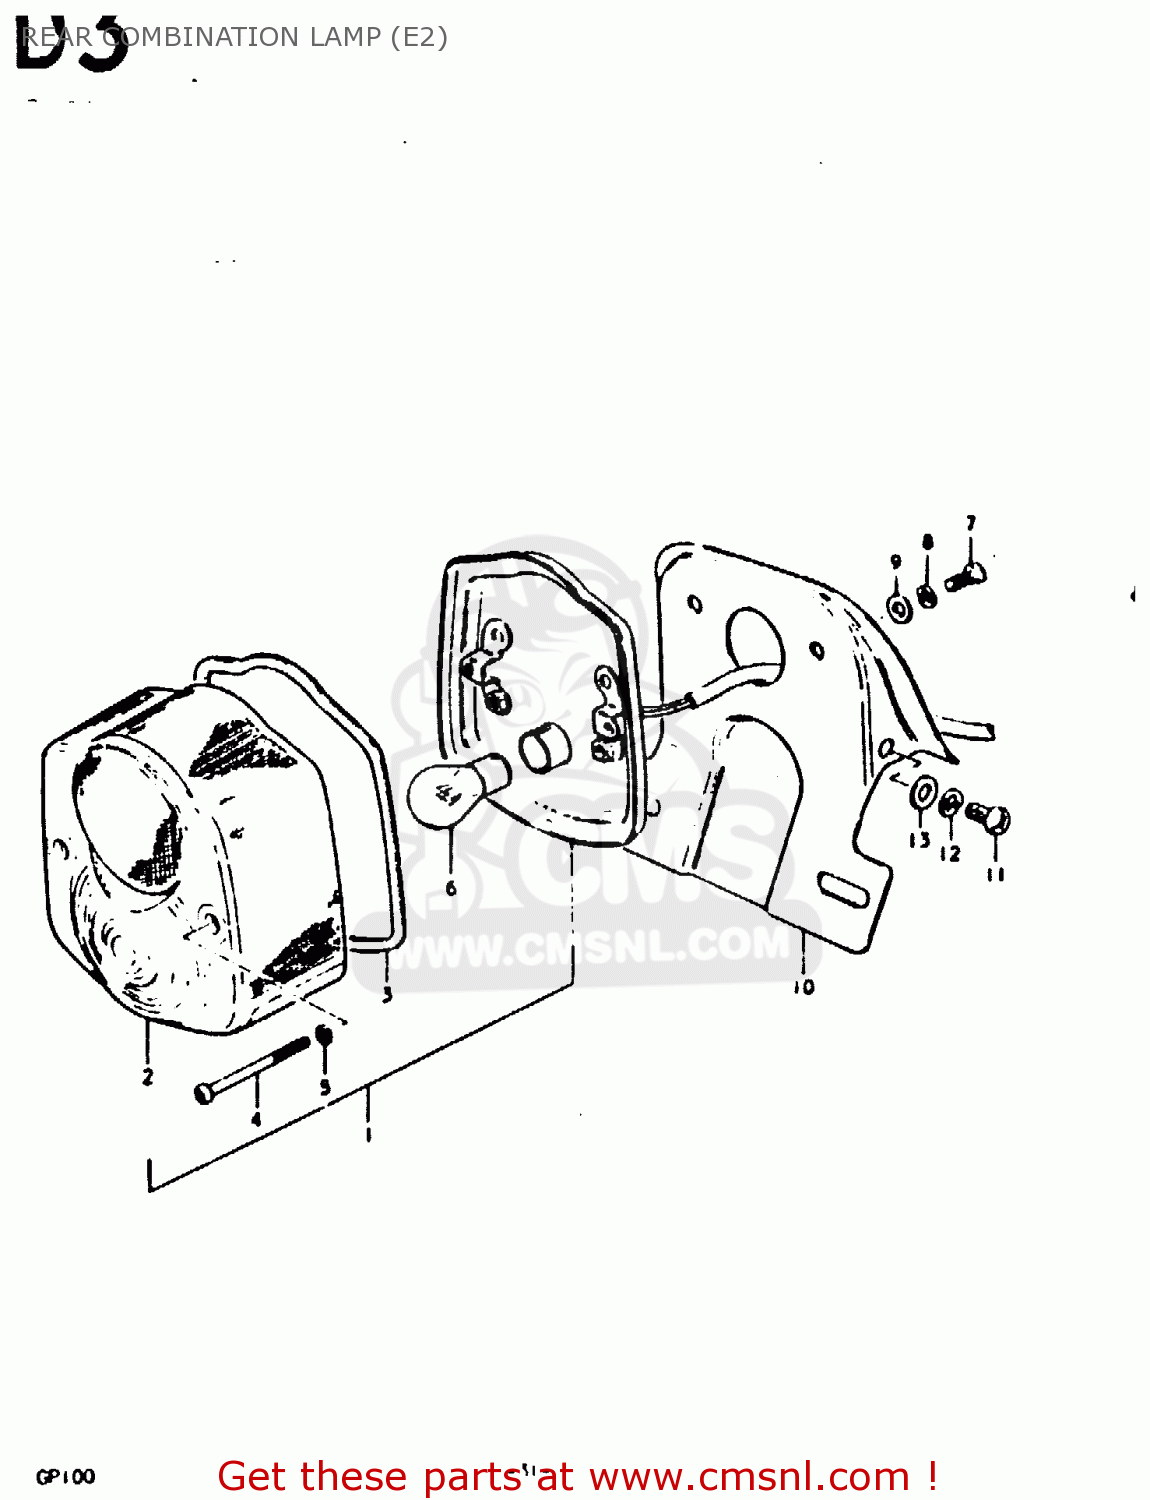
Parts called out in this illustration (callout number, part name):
1	LAMP ASSY, REAR COMBINATION
2	LENS
3	GASKET (NAS)
4	SCREW
5	GASKET (NAS)
6	BULB (6V,21/5W)
7	BOLT
8	LOCK WASHER
9	WASHER
10	BRACKET
11	SCREW
12	LOCK WASHER
13	WASHER
